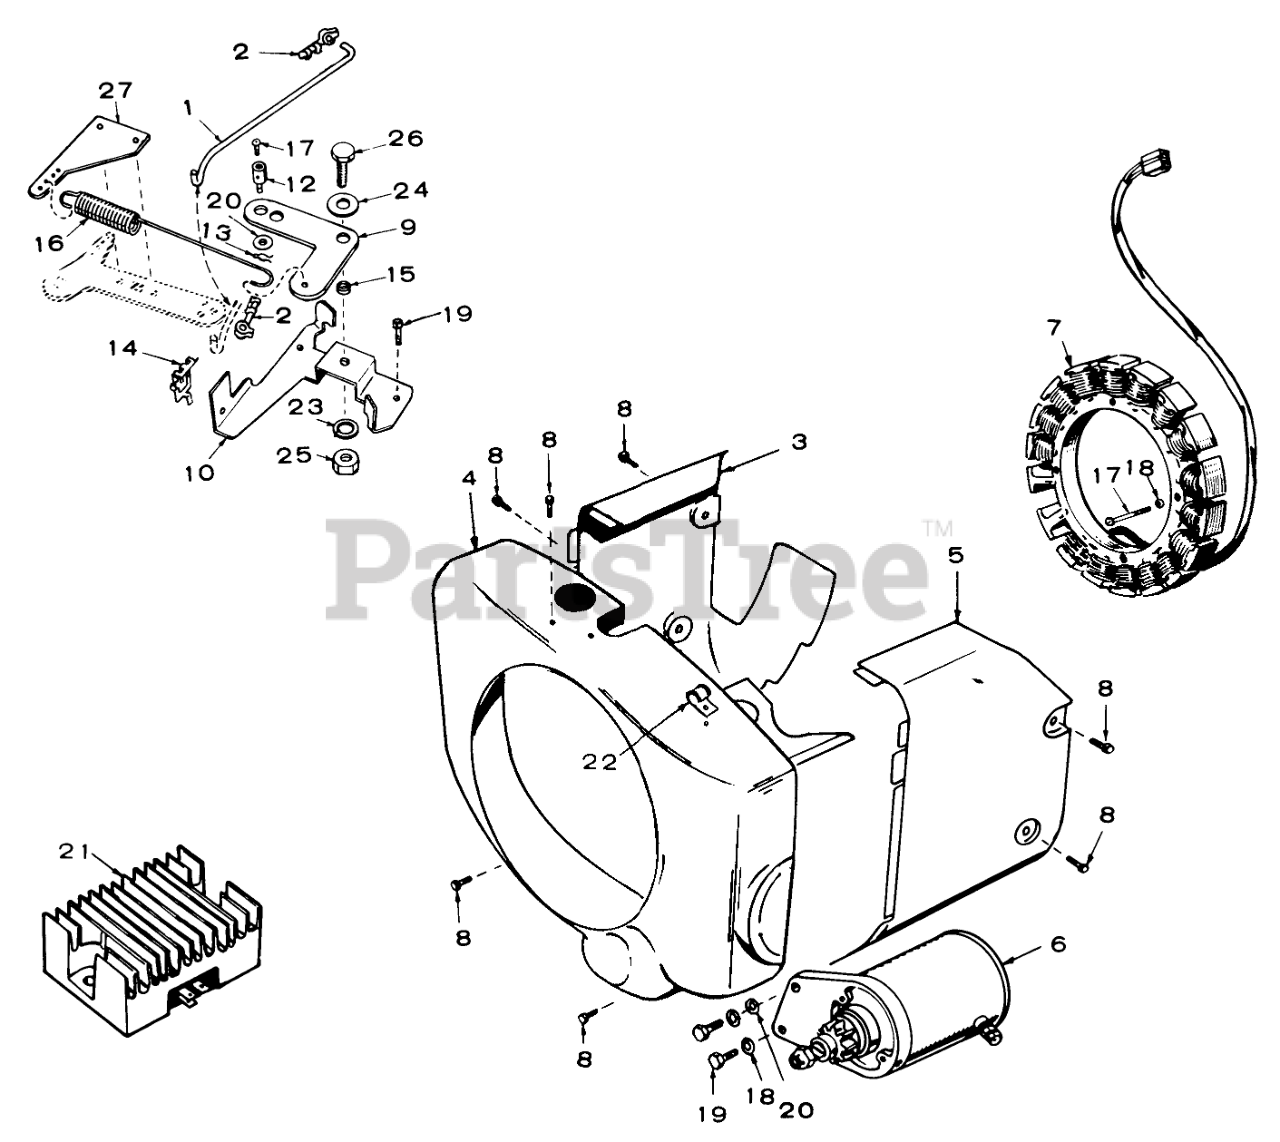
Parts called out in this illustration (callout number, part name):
2	CLIP, GOVERNOR CONTROL ROD
6	MOTOR, STARTING (For Components-See Separate Group)
8	Cylinder Air Housing Mounting
14	Clip, Throttle Cable
17	SCREW, ROUND HEAD
18	WASHER, LOCK
18	Stator Mounting (#10)
18	Lockwasher 5/16 Starter
19	SCREW, HEX CAP
19	Hex Bolt 5/16-18 Starter
20	WASHER, FLAT
23	Lockwasher 1/4
25	Nut 1/4-20
26	Hex Bolt
27	ADAPTOR-GOV ARM
